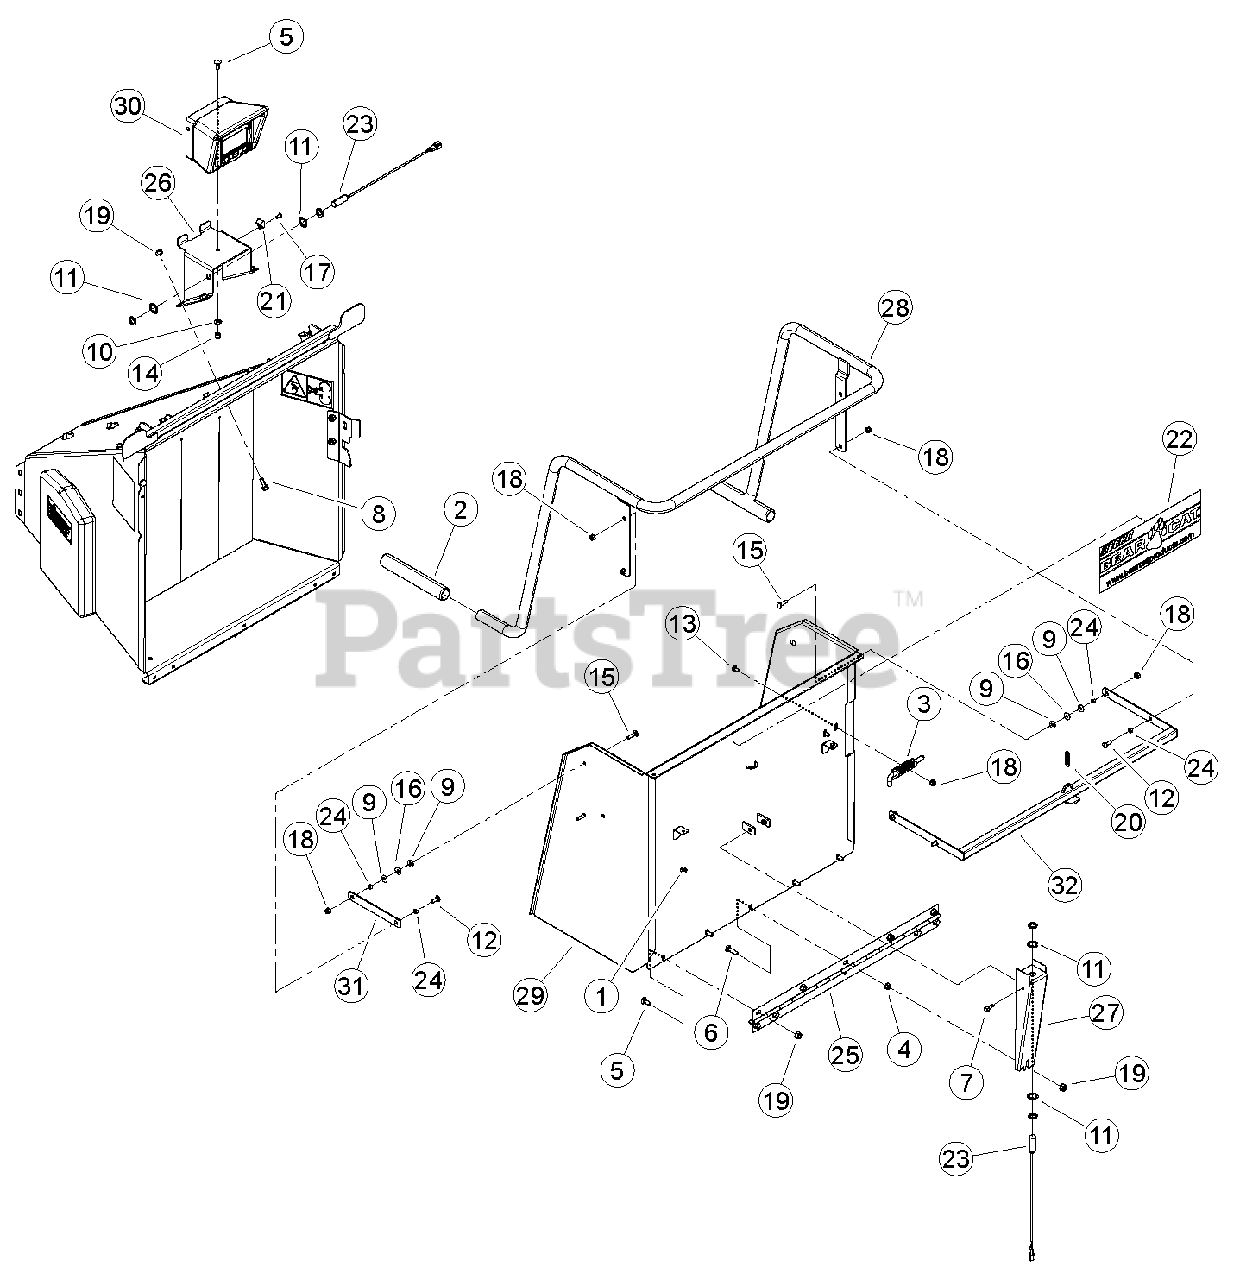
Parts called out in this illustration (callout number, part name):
1	BUMPER, RUBBER
2	GRIP, 1.219 X 10.00
3	LATCH, RH HINGE
4	NUT, 3/8" SERRATED FLANGE NC ZP
5	BOLT, 3/8 X 1" GR5 CRG NC ZP
6	BOLT, 3/8 X 1-1/2" GR5 CRG NC ZP
7	BOLT, 5/16 X 3/4 FLANGE NC
8	BOLT, 3/8 X 1 FLANGE NC
9	WASHER, 5/16" FLAT ZP
10	WASHER, 3/8" SAE FLAT ZP
11	WASHER, 3/4 INTERNAL LOCK
12	BOLT, 5/16 X 1" GR5 CRG ZP
13	BOLT, 5/16 X 3/4 GR5 CRG NC ZP
14	NUT, 3/8" NE NYLOCK ZP
15	BOLT, 5/16 X 1-1/4" GR5 CRG ZP
16	WASHER, 5/16" ID 7/8" OD NYLON FLAT
17	RIVET, AL BLIND 1/4 X 3/4 DOME HEAD
18	NUT, 5/16-18 NYLOCK-FLANGE
19	NUT, 3/8-16 NYLOCK FLANGE
20	SPRING, 1/2 X 2.00 LG ZP
21	CLAMP, CABLE MOUNT
22	DECAL, BEARCAT WEB
23	SENSOR, M18 PROXIMITY (REPLACEMENT PART)
24	SPACER, IDLER PIVOT
25	HINGE, EXTENSION TRAY
26	MOUNT, 5/8/9" DDC
27	MOUNT, 5/8/9" KNEEBAR PROX SENSOR
28	WELDMENT, 8/9" SAFETY KNEEBAR
29	WELDMENT, INFEED TRAY
30	ASSEMBLY, DDC ENCLOSURE
31	LINK, PARALLEL
32	WELDMENT, KNEEBAR PIVOT
